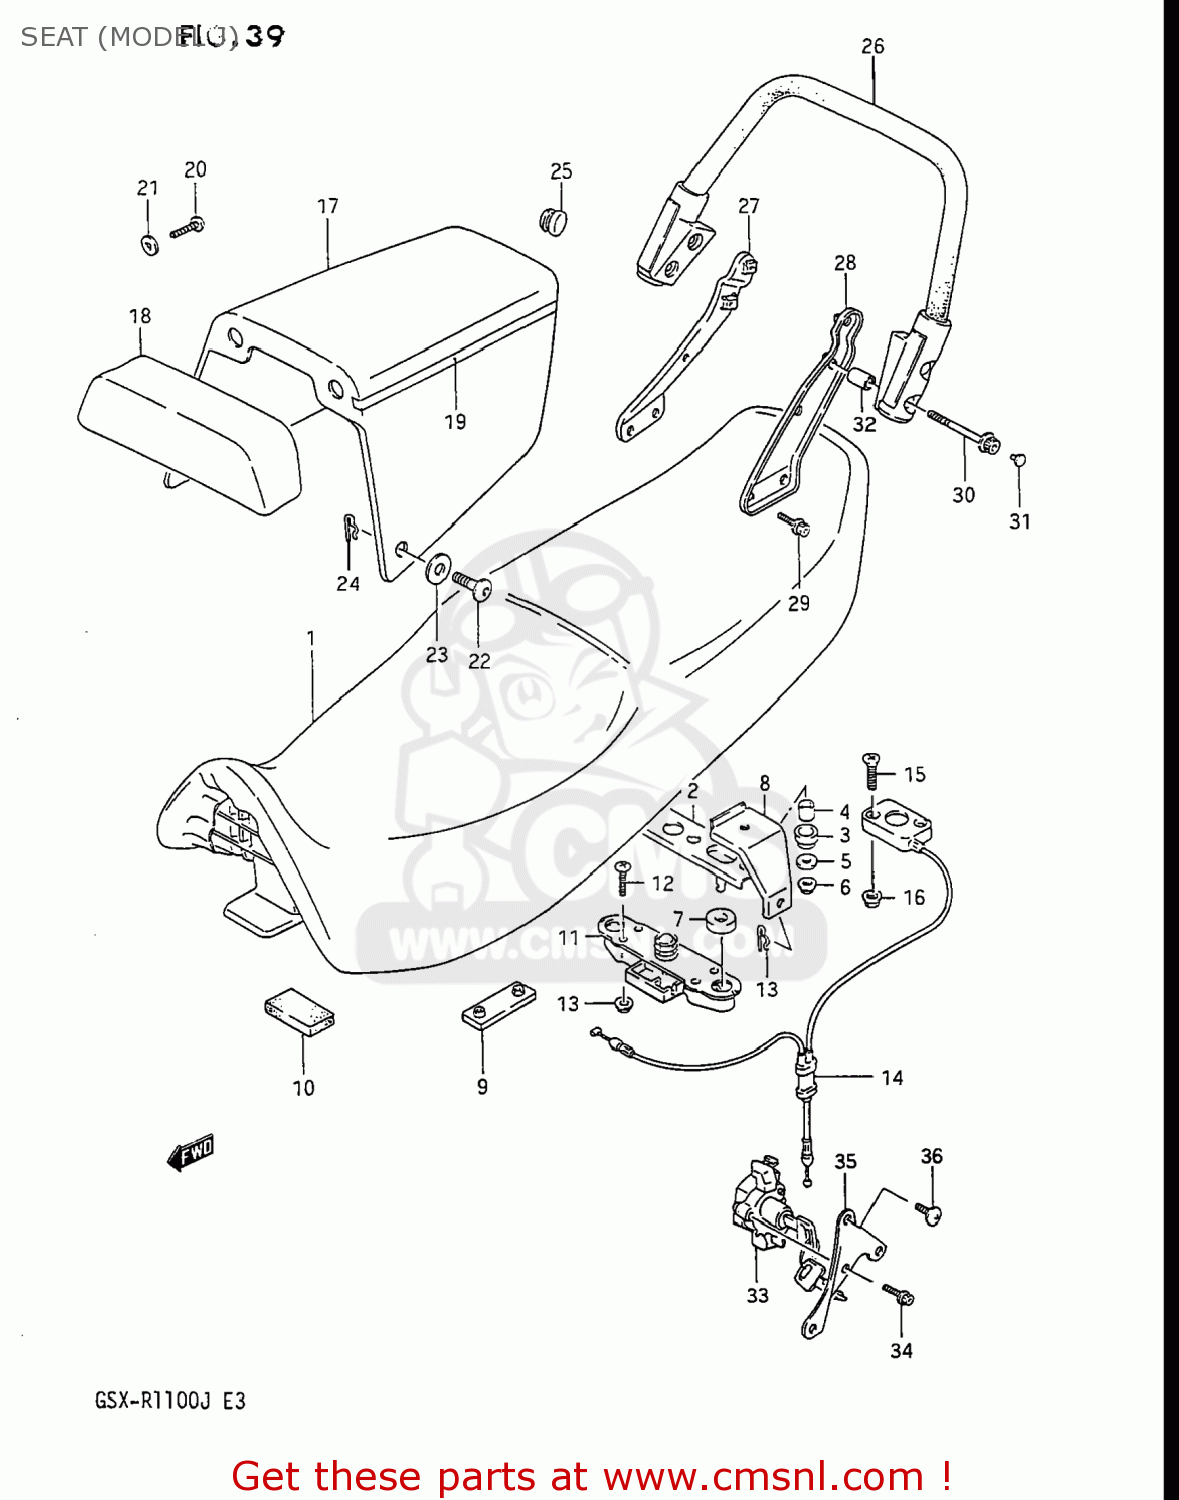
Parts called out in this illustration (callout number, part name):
1	SEAT ASSEMBLY
2	STRIKER,SEAT LOCK
3	CUSHION
4	SPACER
5	WASHER
6	NUT
7	CUSHION
8	PLATE,SEAT GRIP BAND
9	CUSHION
10	CUSHION
11	LOCK ASSY,SEAT STRIKER
12	SCREW
13	NUT
14	BRACKET,SEAT SUPPORT RR
15	SCREW
16	NUT
17	BOX SET,SEAT TAIL
18	BACKREST,SEAT
19	TAPE SET,SEAT TAIL BOX
20	SCREW, CENTER
21	WASHER (6.5X18X1.6)
22	BOLT
23	WASHER(10X25X3.2)
24	CLIP
25	CAP,SEAT TAIL COVER
26	HANDLE,PILLION RIDER
27	PLATE,PILLION HANDLE,R
28	PLATE COMP,PILLION HANDLE
29	BOLT
30	BOLT 5X10
31	CAP(OD:10)
32	SPACER (8.6X13.8X21.5)
33	LOCK SET
34	PLUG ,6X20
35	BRACKET,SEAT LOCK
36	SCREW 6X12
